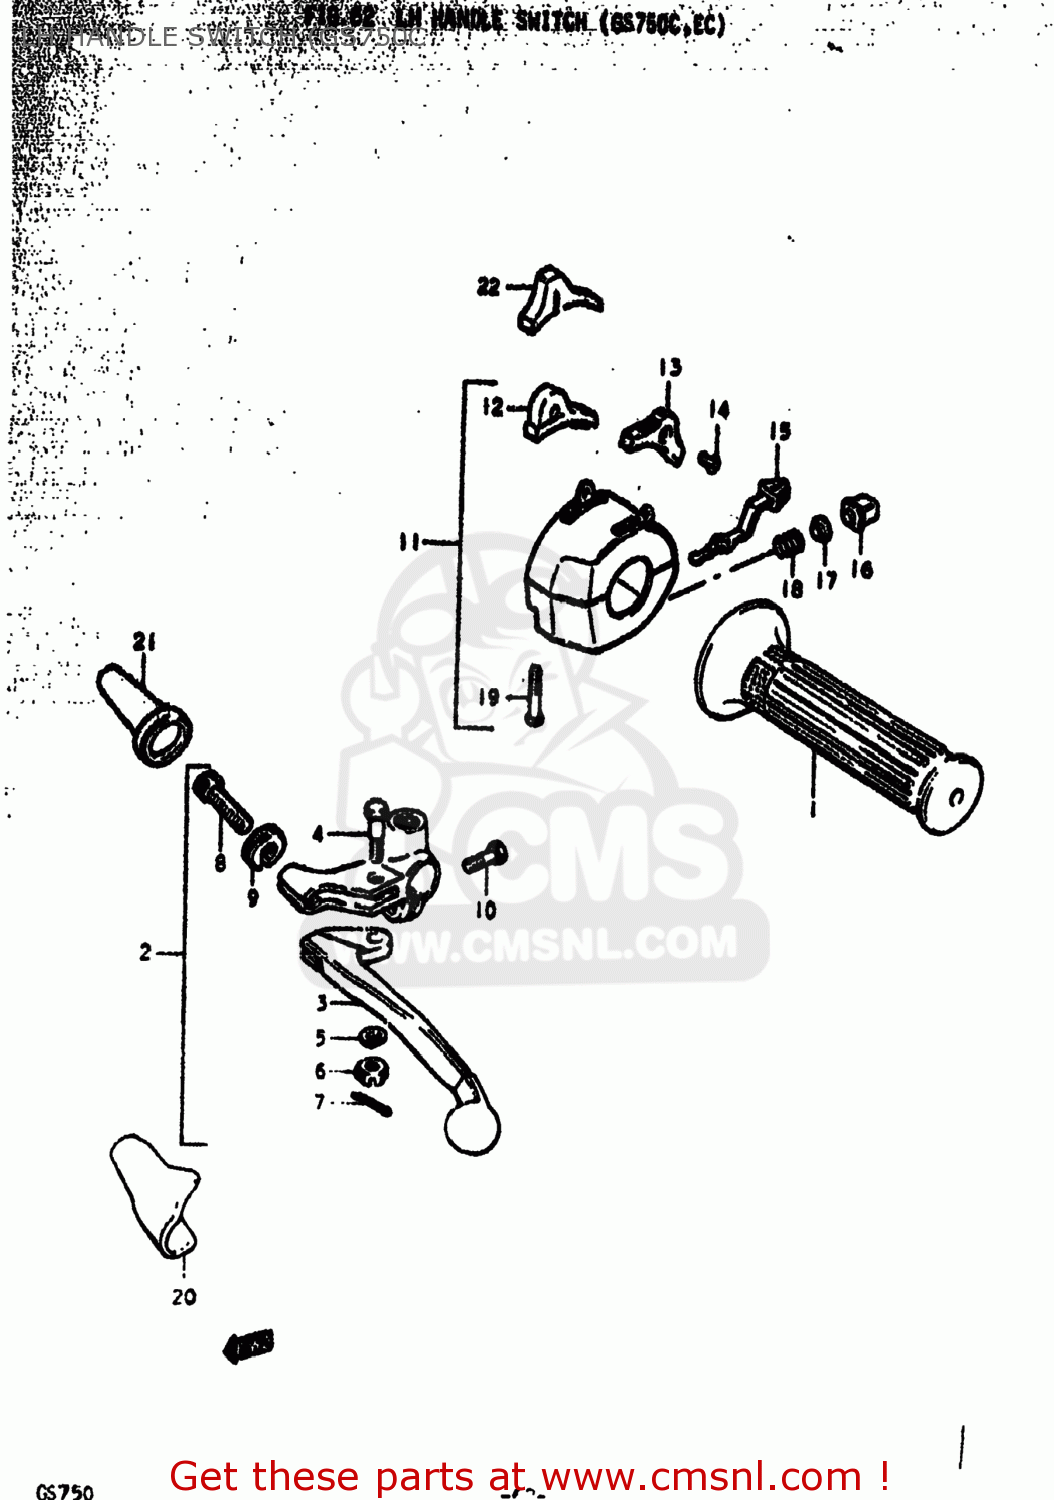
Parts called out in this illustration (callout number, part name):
1	GRIP,L
2	LEVER ASSEMBLY
3	LEVER,CLUTCH
4	BOLT,LEVER
5	LOCK WASHER
6	NUT,LEVER FITTNG
7	COTTER PIN
8	ADJUSTER,CABLE
9	NUT,CABLE ADJUSTER
10	BOLT
11	SWITCH ASSEMBLY,HANDLE,LEFT
12	KNOB,STOP SWITCH
13	KNOB,DIMMER SWITCH
14	SCREW
15	KNOB,TURNSIGNAL
16	BUTTON,HORN
17	CONTACT
18	SPRING
19	SCREW
20	COVER,CLUTCH LEVER
21	BOOT,CLUTCH CABLE
22	KNOB,LIGHTING SWITCH
